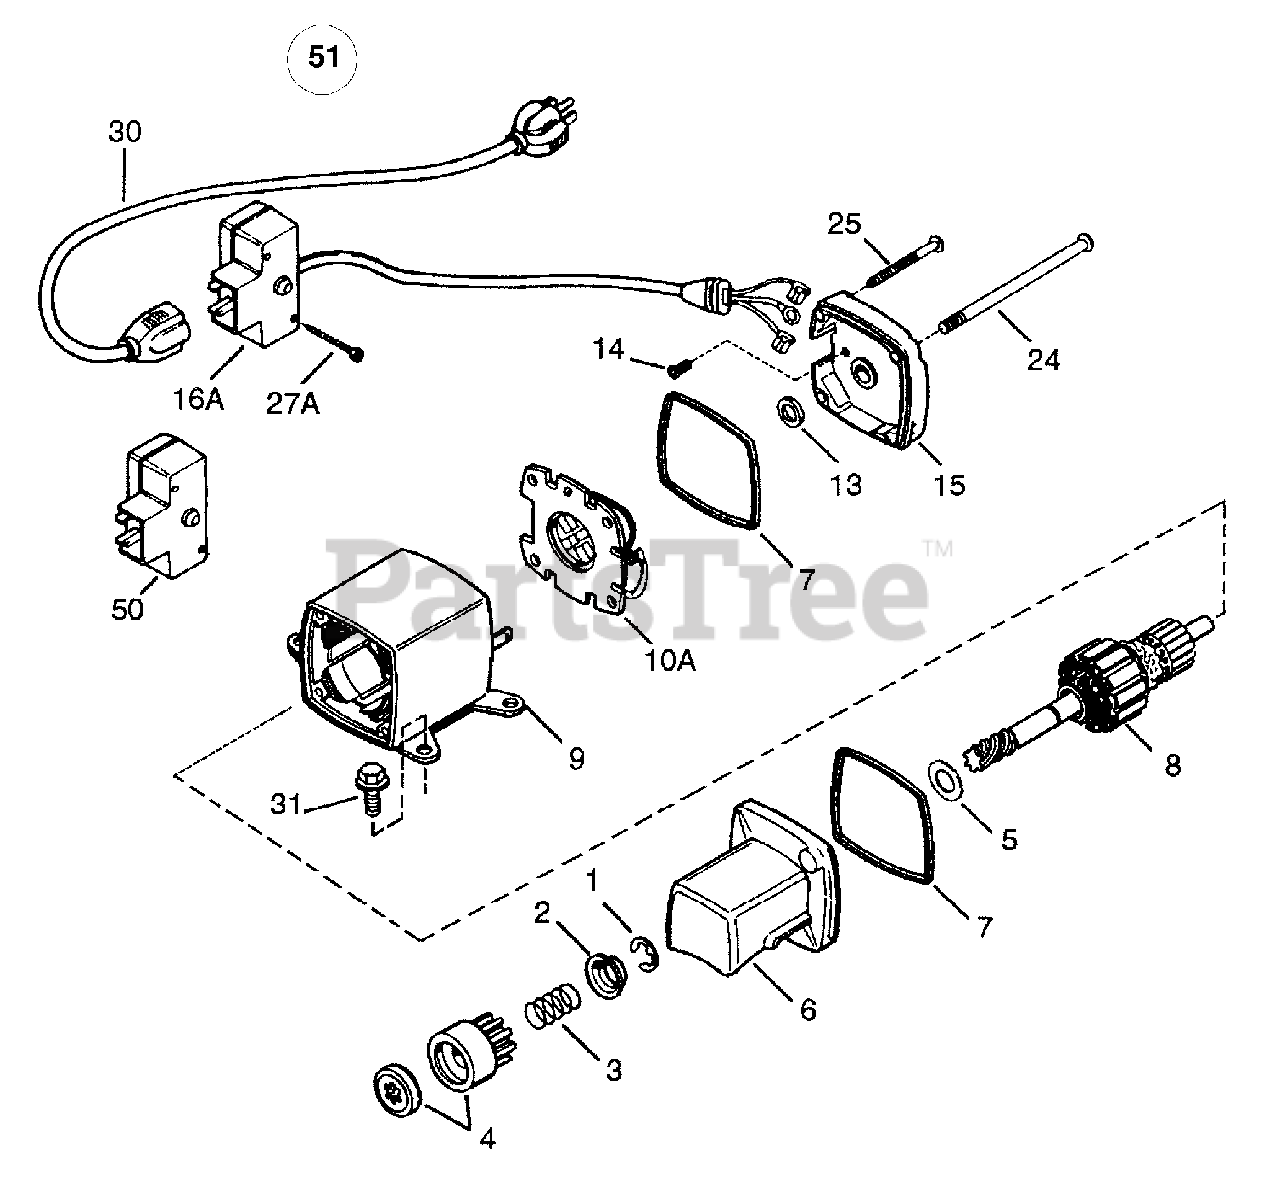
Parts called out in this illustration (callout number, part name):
1	Retainer Ring
2	Spring Retainer
3	Anti-Drift Spring
4	Nut & Gear
5	Thrust Washer
6	Drive End Cap Ass'y
9	Housing Ass'y
10A	Brush & Spring Card Ass'y
13	Thrust Washer
14	Ground Screw
15	Commutator End Cap Ass'y
16A	Switch Box Ass'y
24	Case Bolt
25	Grounding Screw
27A	Screw, 6-32 x 2-1/2"
30	Extension Cord (10' 6")
31	Screw, Torx T-30, 1/4-20 x 23/32"
50	Switch Repair Kit
51	Electric Starter (110 Volt)
